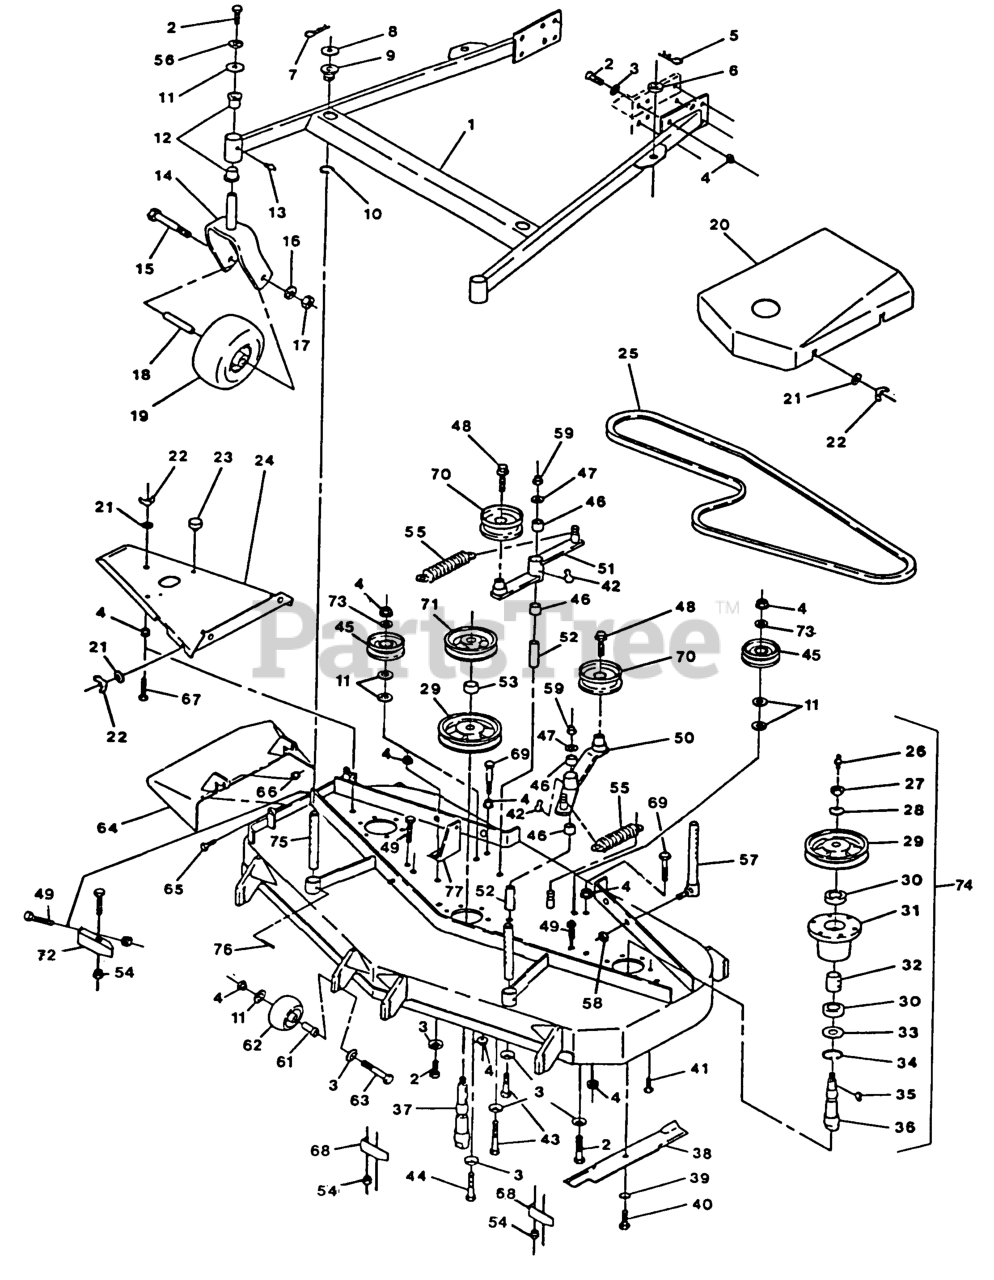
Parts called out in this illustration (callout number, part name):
1	SUPPORT ASSY-FMD60
5	PIN,HAIR COTTER
8	WASHER-FLAT
9	BUSHING-DECK
12	BEARING-FLANGED
22	NUT-WING
24	WLD,DECK COVER
25	BELT-DRIVE, BLADE
28	WASHER-SPRING
29	SHEAVE,BLADE DRIVE
32	SPACER,BEARING
33	SEAL,MECHANICAL DUST
34	RING,SNAP WLDS N5000-244
36	SPINDLE-OUTER BLADE
37	SPINDLE-CENTER BLADE
39	WASHER-SPRING
41	SCRW,TPTTE HH
43	SCREW-HH
45	IDLER,PULLEY
46	SLEEVE-BEARING
50	Arm Weldment Deck Drive Idler
51	Arm Weldment - Deck Idler
52	BUSHING-PIVOT, IDLER
53	SPACER-TUBE
55	SPRING-EXTENSION
61	BUSHING-ROLLER
62	ROLLER-SCALP, ANTI
70	IDLER,PULLEY
72	WLD,BAFFLE DISCHARGE
74	CH-52&60 OUTER CUTTR
75	ROD,DECK SUPPORT
77	BRACKET,SPRING ANCHOR
